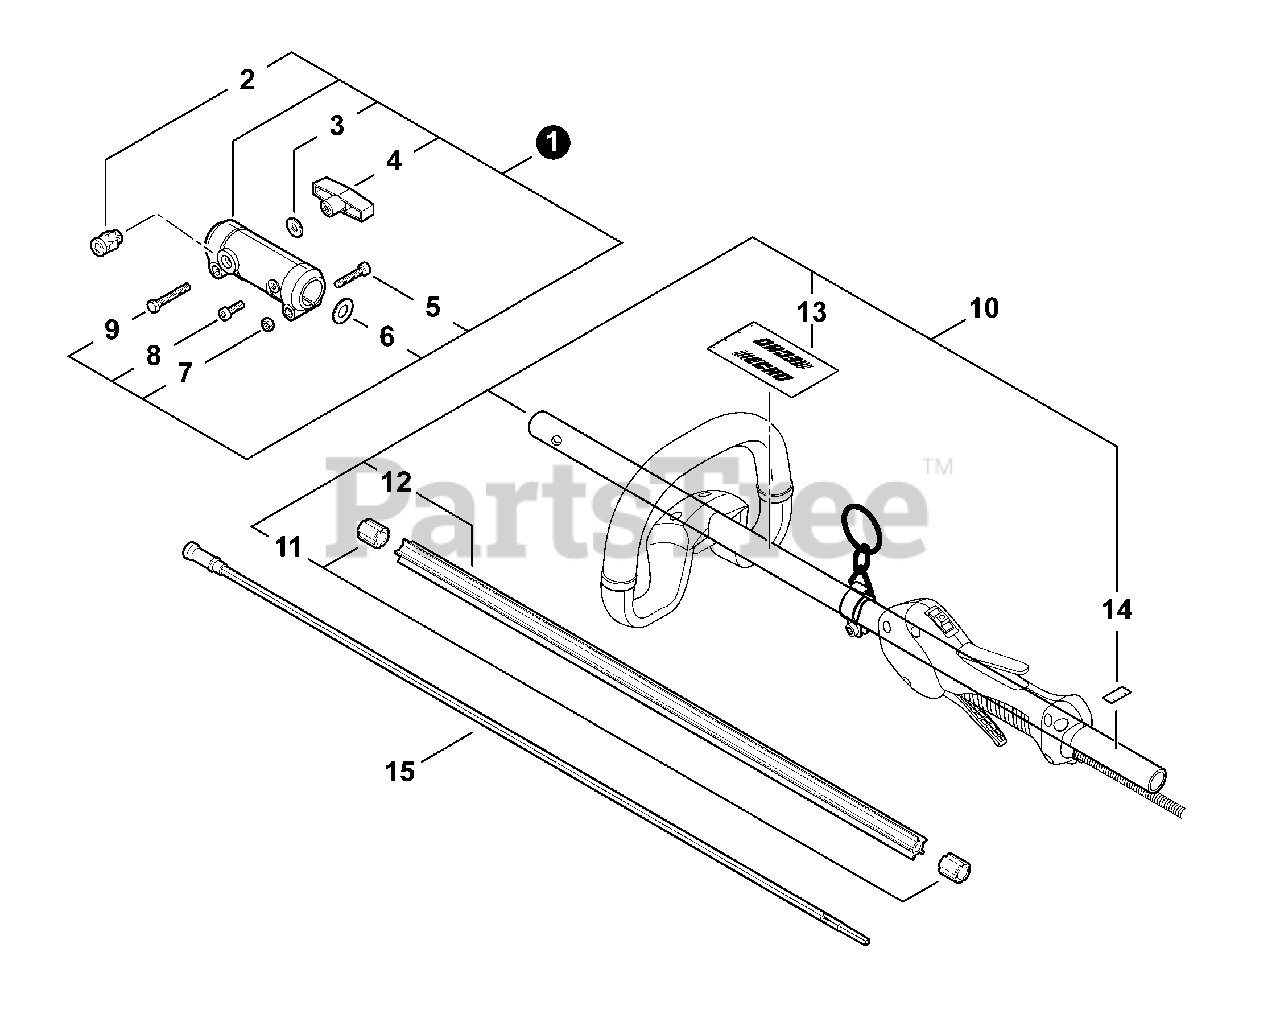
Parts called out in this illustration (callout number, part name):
1	COUPLER ASSY
2	LATCH ASSY
3	WASHER 6.6×20×1.6
4	KNOB, FASTENER
5	BOLT, TORX 6×25
6	WASHER 18 SPR STEEL
8	BOLT, TORX 5×10
9	BOLT 6×40
10	MAIN PIPE ASSY
12	LINER - FLEXIBLE
13	LABEL, HANDLE LOCATION
14	LABEL - ALIGNMENT
15	DRIVESHAFT - FLEXIBLE
